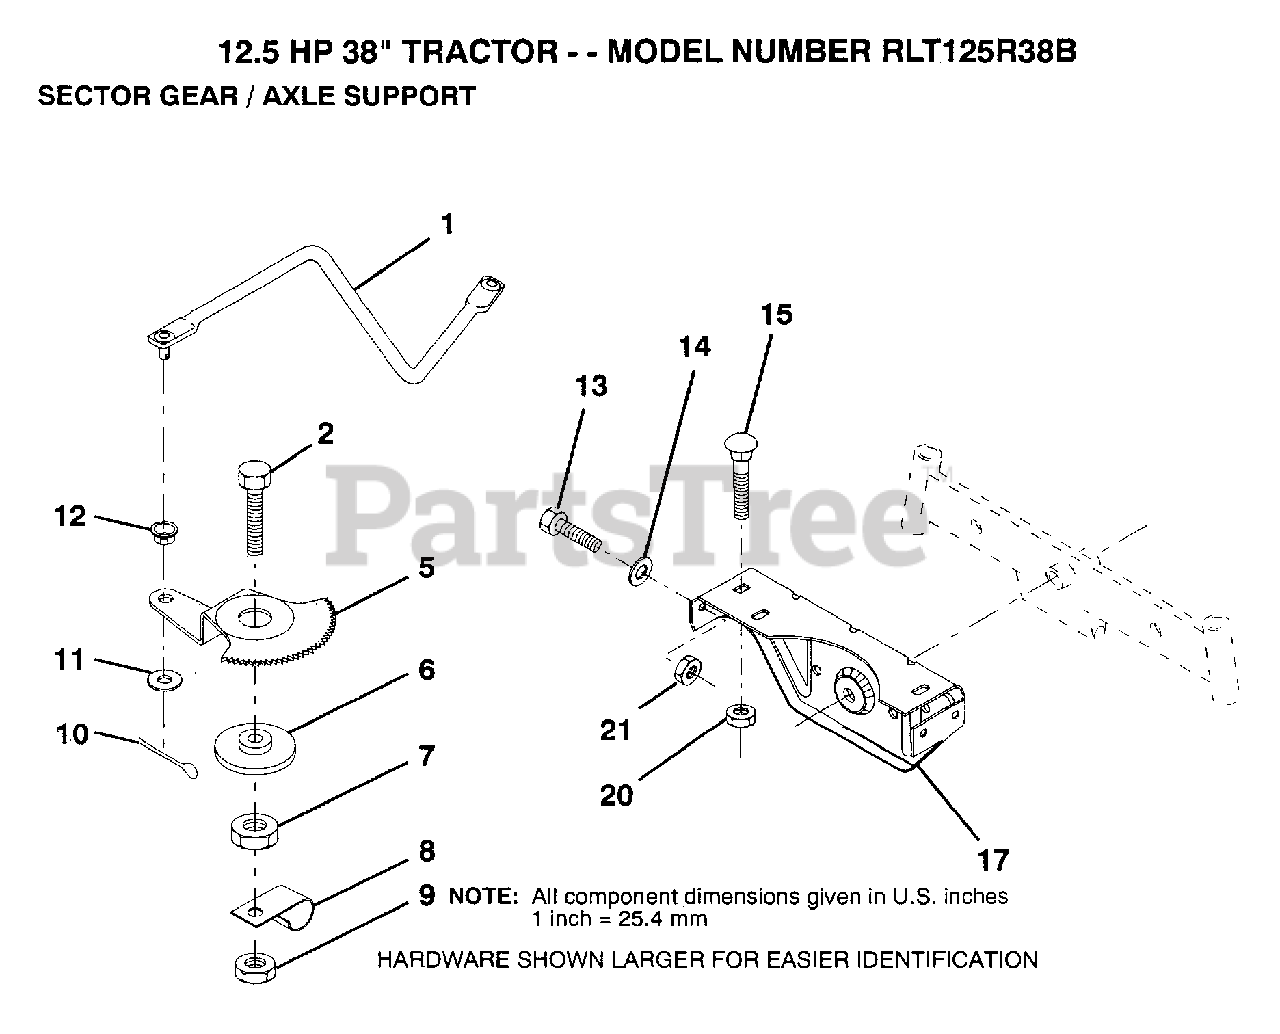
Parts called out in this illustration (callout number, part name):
1	DRAG LINK
2	"BOLT,HEX"
5	GEAR SECTOR
6	BUSHING
7	NUT
8	CLIP INSULATOR
9	NUT LTV
10	COTTER PIN
11	WASHER
12	BUSHING.DRAGLINK
13	BOLT
14	WASHER
15	BOLT
17	SUPT AXLE FRONT
